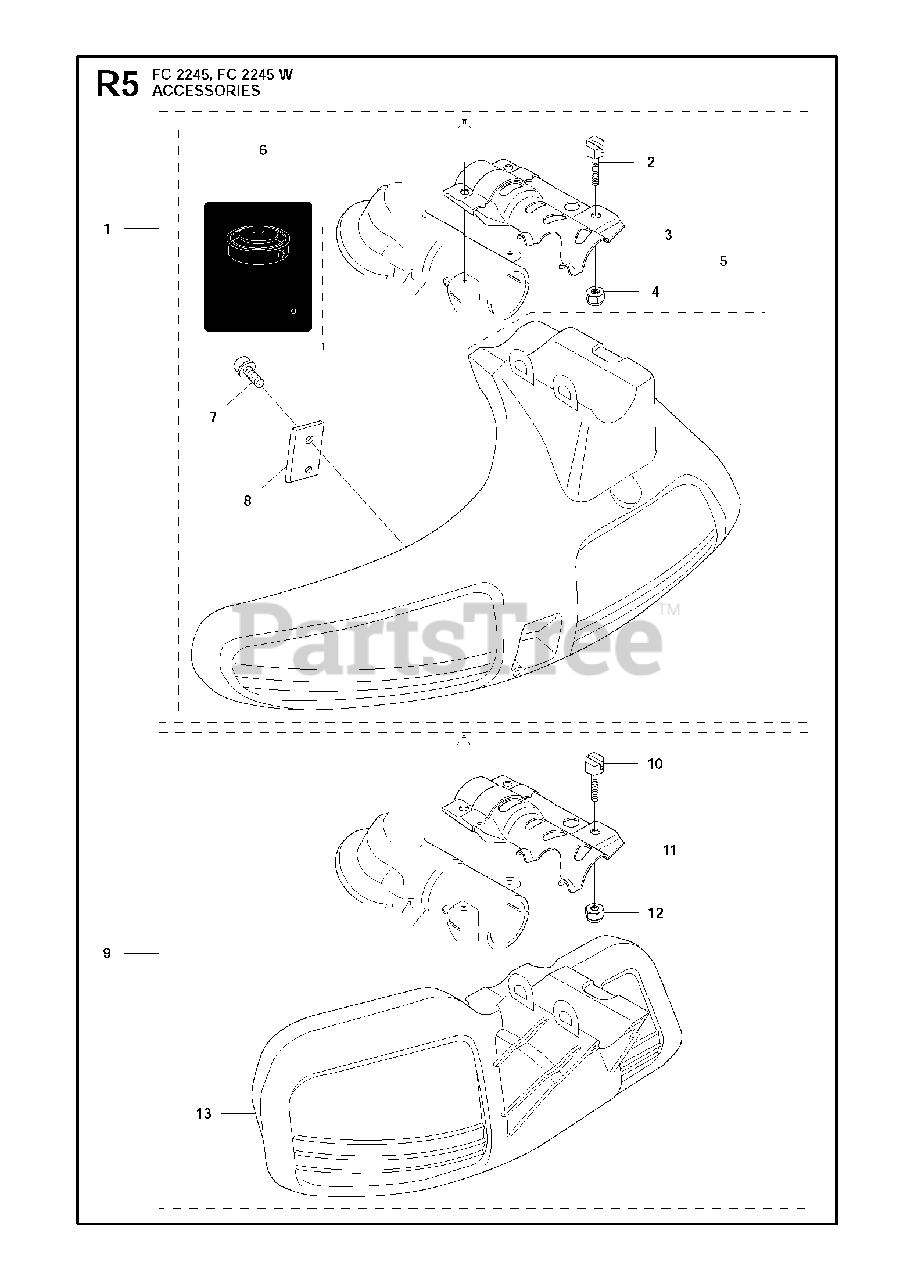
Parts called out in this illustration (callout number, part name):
1	SPLASH GUARD KIT
2	SCREW
3	PLATE
4	LOCKNUT M6
5	PROTECTOR
6	DECAL
7	SCREW
8	BLADE
9	TRIMMER GUARD COMPL
10	SCREW
11	PLATE
12	LOCKNUT M6
13	BLADE GUARD
